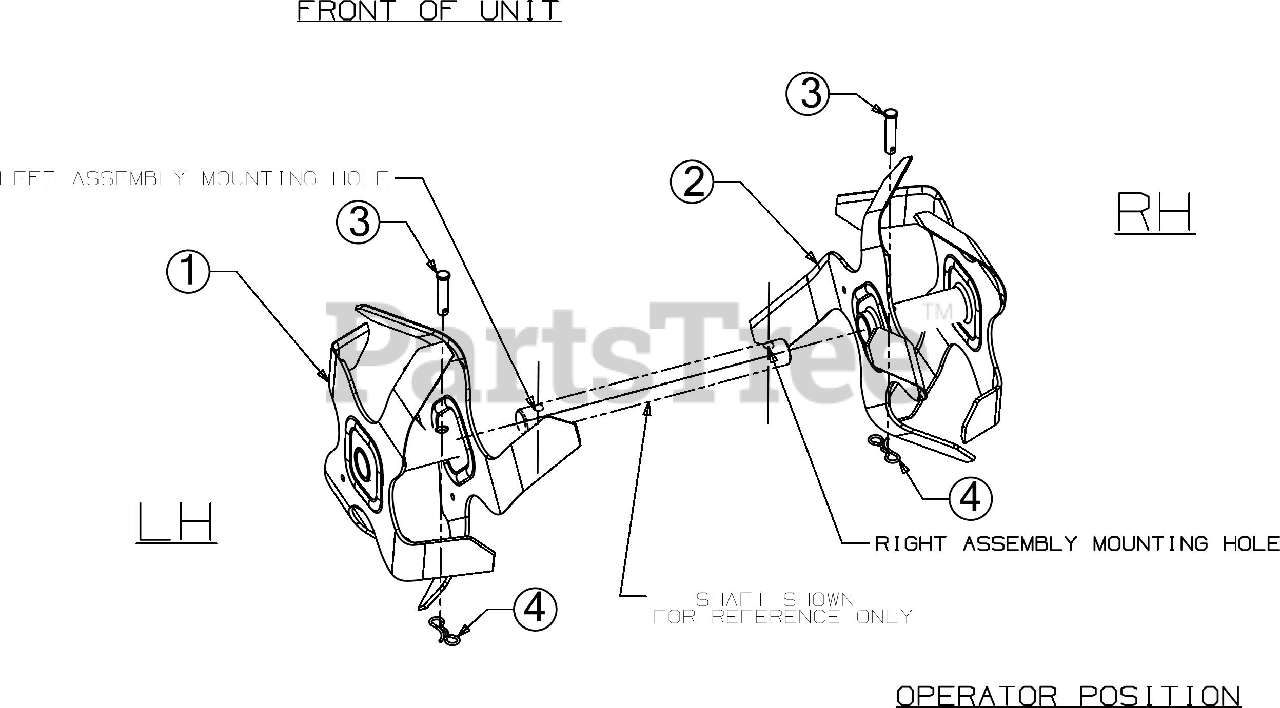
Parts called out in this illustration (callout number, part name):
1	TINE ASSEMBLY (LH)
2	TINE ASSEMBLY (RH)
3	CLEVIS PIN .375 x .1.75
4	PIN:COTTER
